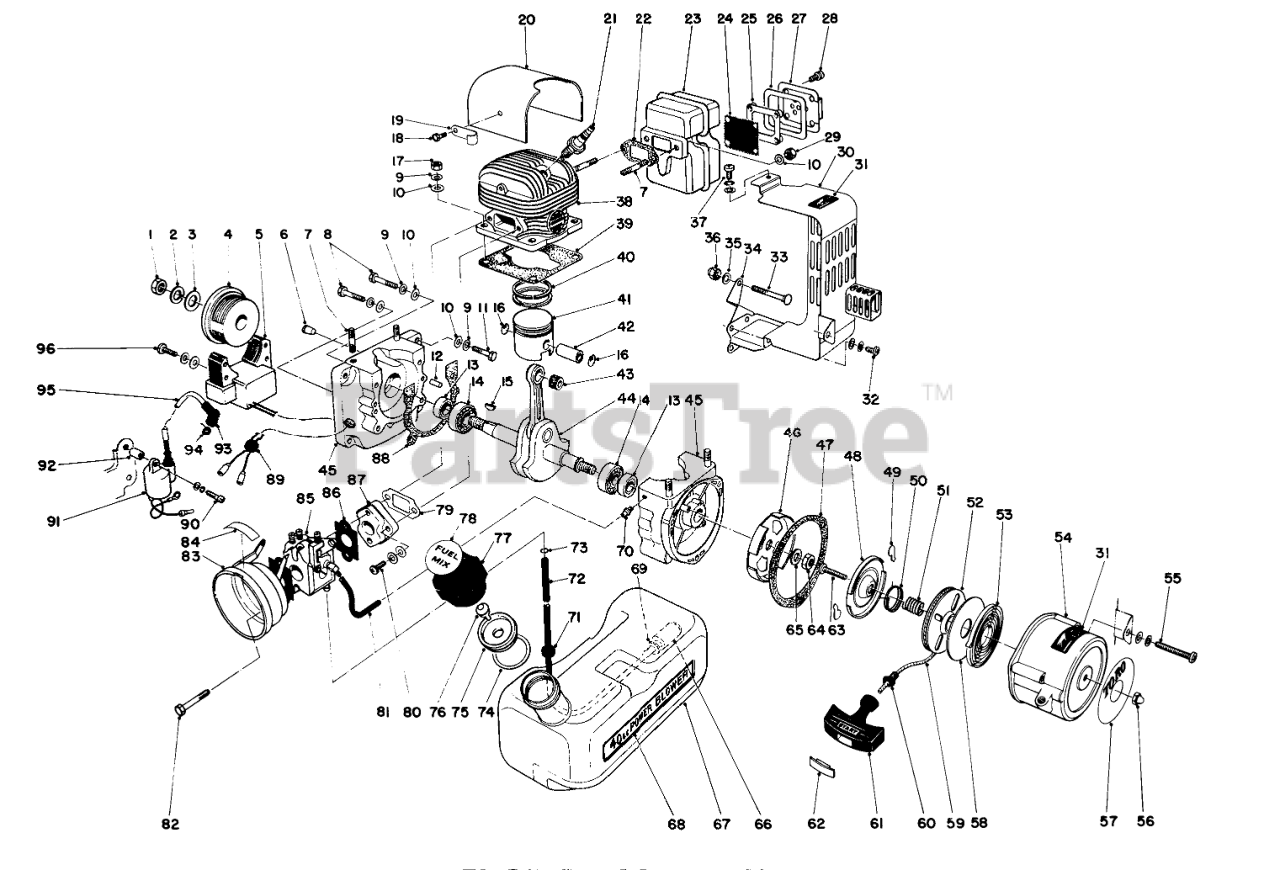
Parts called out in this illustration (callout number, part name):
2	Spring Washer
3	Washer
4	Rotor
5	C.D.I. MODULE - ECHO
9	Washer
10	Washer
12	Knockpin
13	Oil Seal
14	Ball Bearing
15	Woodruff Key
16	CIRCLIP PISTON PIN
19	Clamp
20	Cylinder Cover
21	Spark Plug
22	Gasket Muffler
23	Muffler Assembly (Incl. Ref.#22-30, 35 & 7)
24	Screen
25	Seat Screen
26	Packing Holder
27	Holder Screen
28	Screw
29	LOCKNUT
30	MUFFLER COVER
31	Decal-Hot Surface
32	SCREW
33	Bolt, Elbow
34	Bracket-Muffler Cover
35	WASHER
36	Capnut
37	SCREW W/WASHER
38	Cylinder
39	Packing Cylinder Base
40	PISTON RING
41	Piston
42	Piston Pin
43	Needle Bearing
44	Crankshaft Assembly
45	Crankcase Set
46	PAWL CATCHER
47	STARTER CASE GASKET
48	FRICTION PLT
49	RATCHET
50	RATCHET SPRING
51	SPRING
52	Recoil Drum
53	REWIND SPRING
54	Starter Case
55	SCREW
56	Cap Nut
57	Decal-Toro
58	Side Plate, Starter
59	Starter Rope
60	Rope Guide
61	Starter Handle
62	Cap, Starter Handle
63	Screw
65	Washer
66	Fuel Strainer
67	Fuel Tank
68	Decal-40cc
69	Washer
70	Connector
71	GROMMET
72	FUEL PIPE
73	Clip Fuel Pipe
74	FUEL TANK GASKET
75	Holder, Check Valve
76	Check Valve
77	FUEL TANK CAP - WILLMAR
78	Decal-Fuel Mix
79	GASKET
80	SCREW
83	CLEANER CASE-WILLMAR
84	Decal-Caution
85	CARBURATOR ASM
86	GASKET
87	INSULATOR
88	Packing, Crankcase
89	Grommet
90	Screw
91	IGNITION COIL
92	Spacer
93	Cap-Spark Plug
94	Coil Spring-Plug Cap
95	Sleeve
